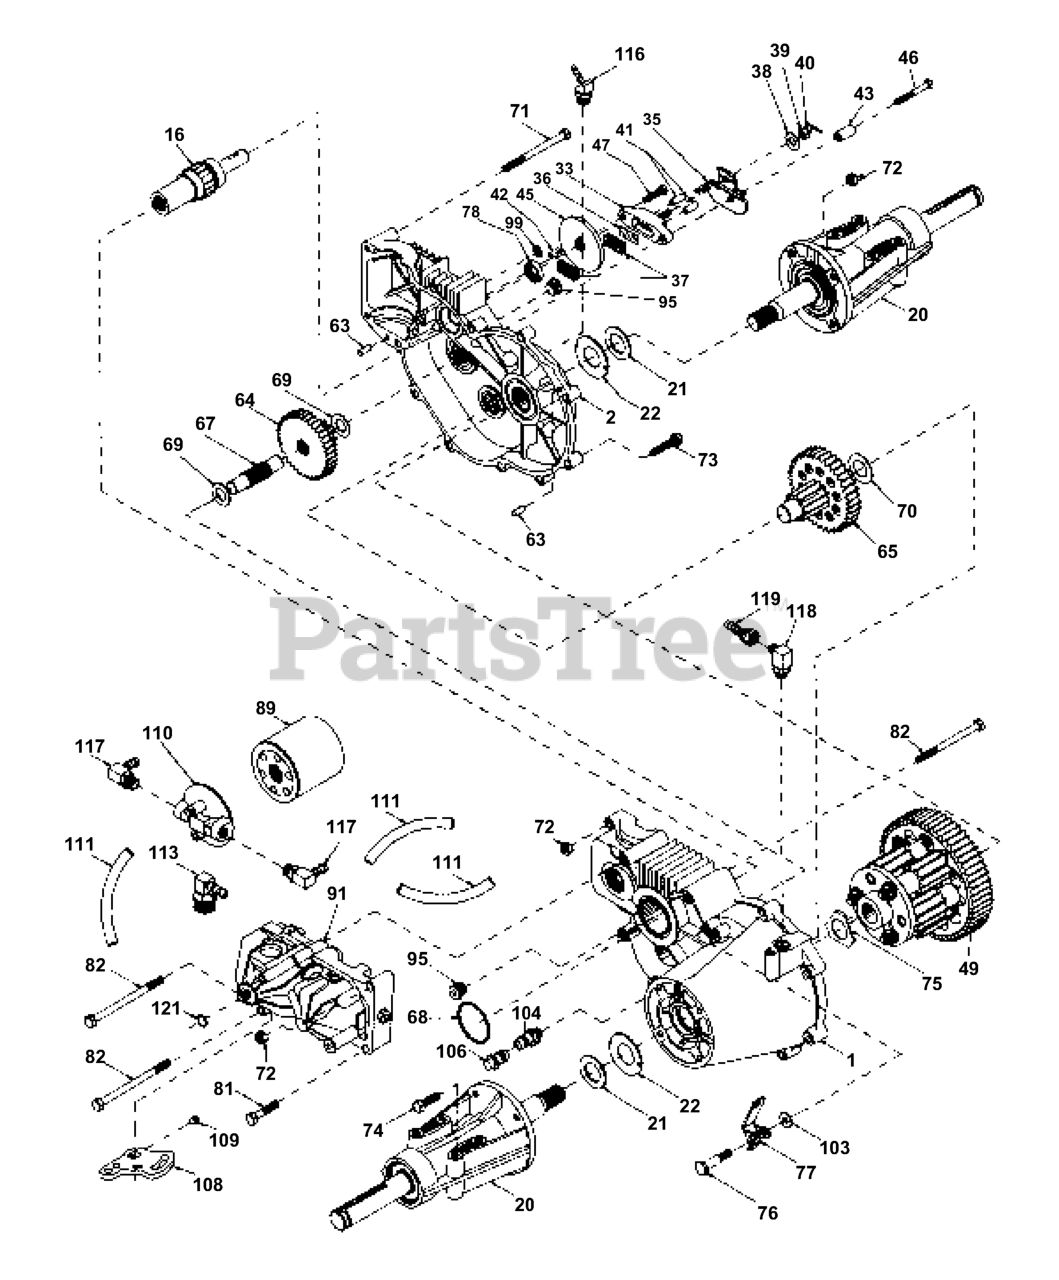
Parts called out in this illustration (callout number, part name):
1	HOUSING.TRANSAXLE.70536
2	ASSEMBLY, RH HOUSING
16	BRAKE SHAFT KIT #62877
20	AXLE.MOUNTING.HORN.70087
21	WASHER 44805
33	BRAKE YOKE ASSEMBLY
35	BRACE ARM 50214
36	PUCK PLATE 44134
37	BRAKE PUCK (44132)
38	WASHER .34X.88X.06.44130
39	CASTLE NUT
40	PIN.COTTER.44101.
41	BRAKE PIN 44127
42	KEY.HIPRO.44143
43	SPACER 50259
45	BRAKE.DISC.44090.
46	BOLT 44276
47	BOLT W/NYLOCK 44433
49	DIFFERENTIAL ASSEMBLY
63	DOWEL.PIN.44757.HYDRO
64	GEAR 17T 44775
65	PINION DR FINAL 70051
67	JACKSHAFT.44779.HYDRO
68	O-RING #44781
69	WASHER.44795.
70	WASHER.44794.HYDRO
71	BOLT HXHD 44827
72	HEX LOCK NUT, 5/16-18
73	BOLT, HEX5/16-18X1-1/2
74	HEX CAP SCREW, 5/16-18X1
75	WASHER.DIFFERENTIAL.44880.HYD
76	BOLT.SHOULDER.44785.
77	FREE WHEEL ACTUATING ARM 44786
78	SEAL OIL 70719
82	BOLT 5/16 44820
89	FILTER
91	PUMP BD-10C-118
95	PLUG.9005110-5600
103	WASHER 50169
104	CAP, VENT ASSY
106	O-RING KIT 70110
108	ARM CONTROL 45007
109	SCREW.SET.50018
110	FILTER HEAD 50207 HYDRO
111	HOSE.50208.HYDRO
113	FITTING.9/16 SAE.50210.
116	FITTING.9/16 SAE.50213.
117	FITTING 50249 HYDRO
118	FITTING 90 DEG #6 FLARE MALE
119	FITTING 90 DEG #6 FEMALE SAE
121	RING RETAINING 2003016
